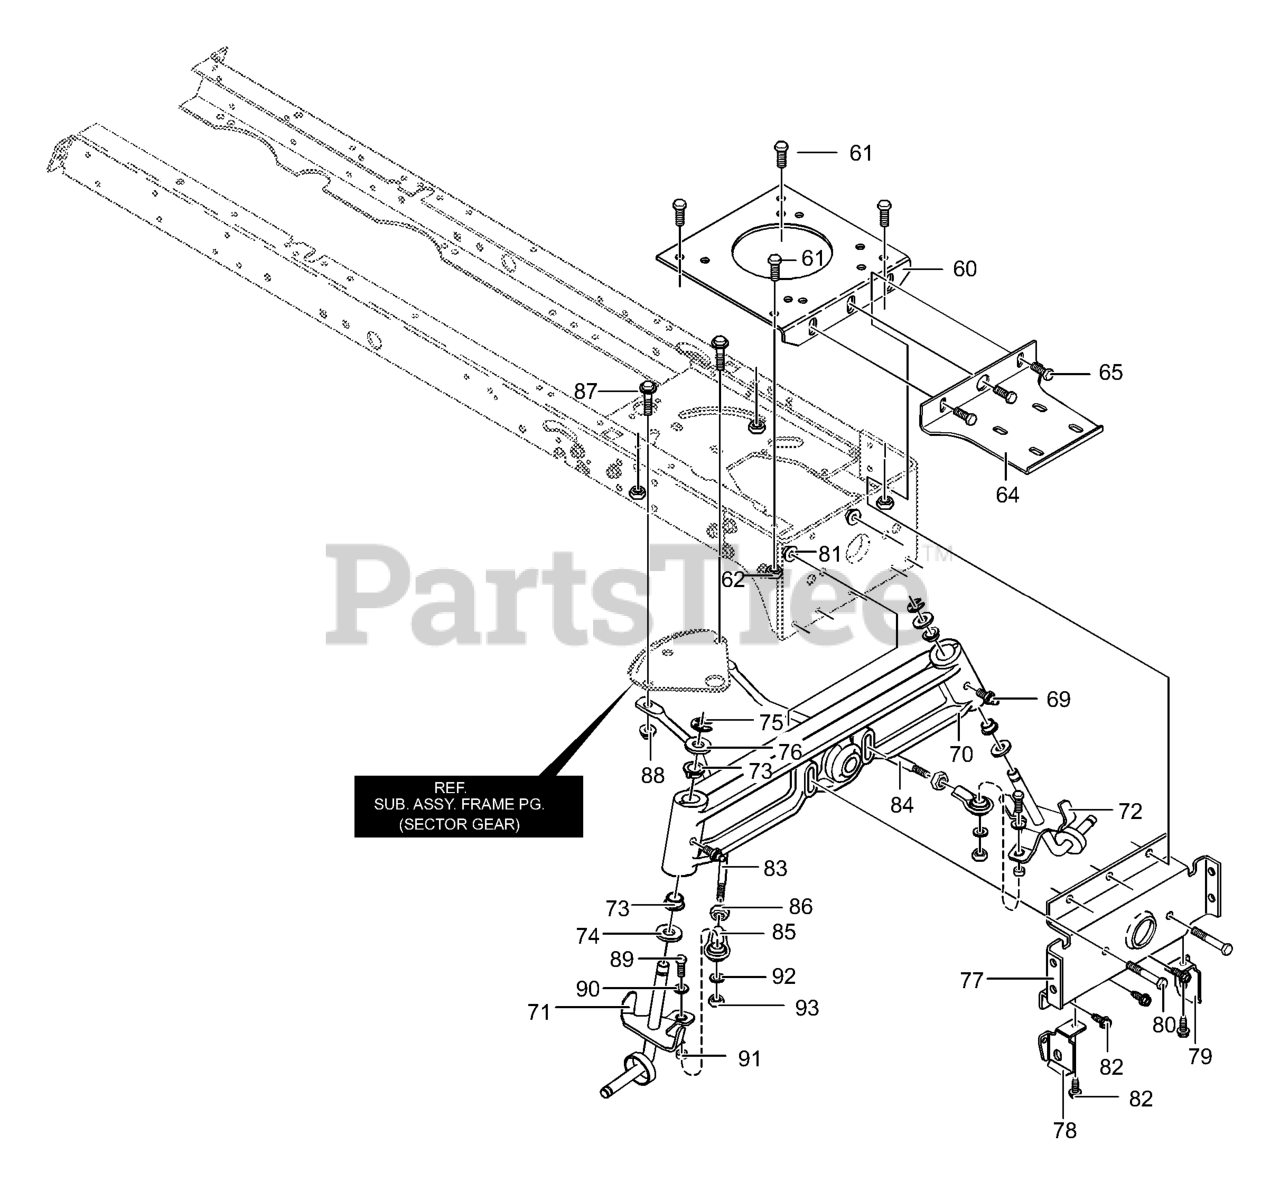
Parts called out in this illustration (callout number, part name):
60	Engine Plate
61	Screw, .312-18x.75
62	Nut, 5/16-18
64	Bracket, Muffler Mount
65	Screw, .312-18x.75
69	Zerk, Grease Fitting
70	Axle, Cast Machined
71	Spindle, RH
72	Spindle, LH
73	Bearing, Spindle
74	Washer, .766IDx1.62ID
76	Flat washer
77	Hanger, Axle
78	Hanger, Deck RH
79	Hanger, Deck LH
80	Screw, 5/16-24 x 2.75
81	Nut, .32-24 Flangelock
82	Screw, .5/16-24X2.75
83	Rod, Drag Link, RH
84	Rod, Drag Link, LH
85	Tie Rod End 1/2-20
86	Nut, 1/2-20 Hxjam
87	Bolt, HHSH
88	Nut, .38-16 Flng Ctrlk
89	Bolt, HHSH 3/8-16
90	Flat washer
91	Spacer, Sleeve
92	Flat washer
93	Nut, 3/8-16 Reghexctrlk
